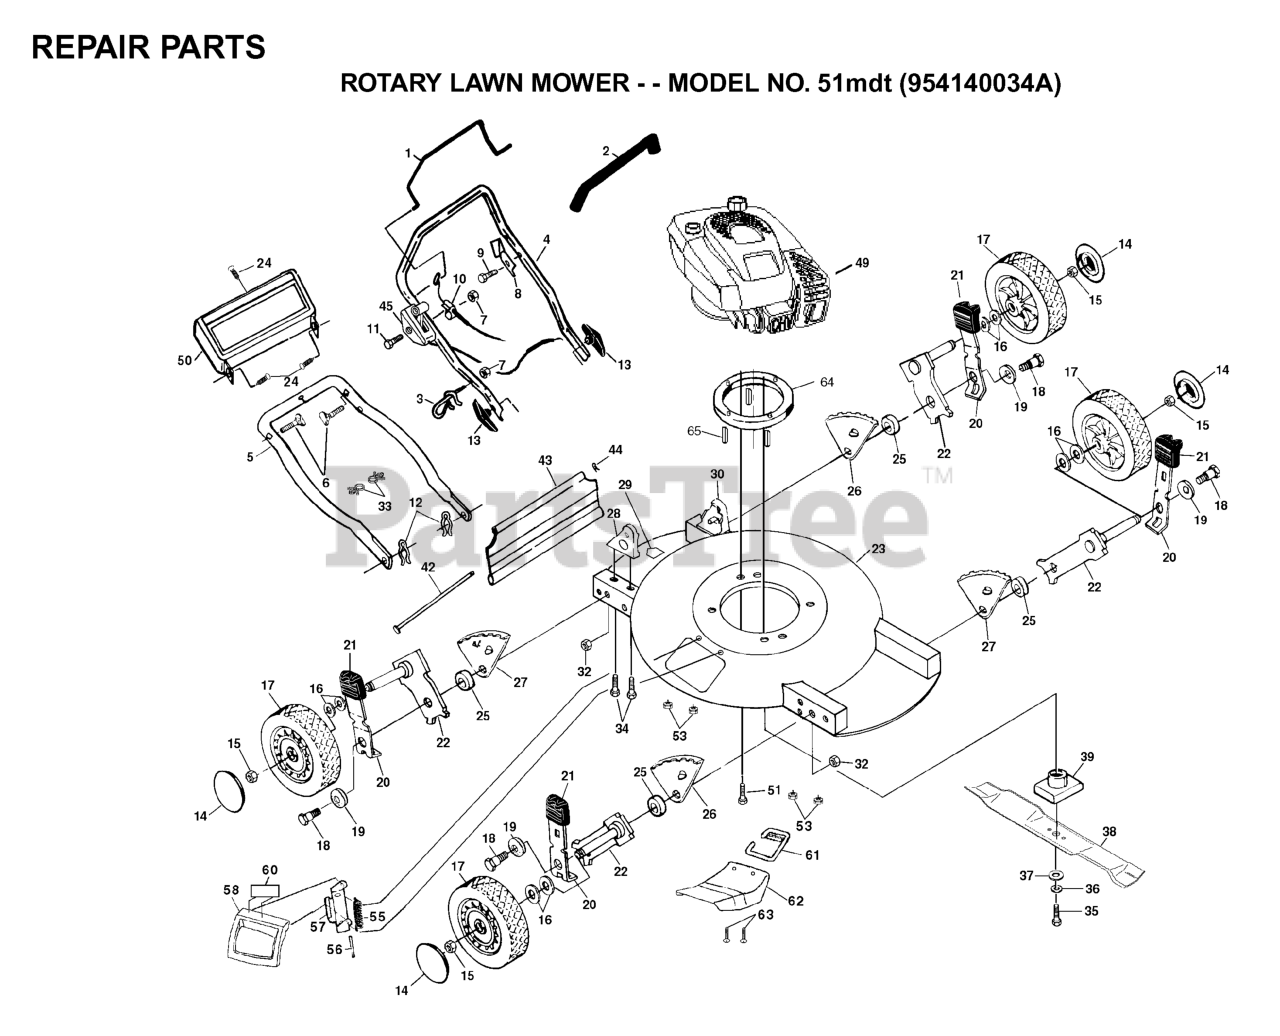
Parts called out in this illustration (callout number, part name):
1	CONTROL BAR/BLACK
2	HANDLE GRIP
3	ROPE GUIDE
4	UPPER HANDLE
5	HANDLE, LOWER
6	HANDLE BOLT
7	NUT
8	BRACKET UPSTOP
9	TAPPING SCREW
10	CABLE.MZR.51.RT.SP./PU.
11	SCREW 1/4-20 X 2.12
12	HAIRPIN COTTER
13	HANDLE KNOB
15	HEX FLANGE LOCKNT
16	WAVE WASHER
18	BOLT
19	WASHER.BELLEVILLE (3 2 LB)
20	SELECTOR SPRING
21	SELECTOR KNOB
22	AXLE ARM
25	RP SPACER HT ADJ
26	WHL ADJ BRKT RF/LR
27	WHL ADJ BRKT LF/RR
28	HDLE BRKT ASSY RH
29	DECAL HYT
30	HDLE BRKT ASSY LH
32	LOCKNUT PM
33	CLIP CABLE SNAP
34	SELF-TAPPING SCREW 5/16-18X3/4
35	SCREW, HEX HD 3/8-24 X 1-3/8
36	LOCKWASHER
37	WASHER,HARDEN
38	BLADE.20.MULCH.(50DK,6020MD)
39	BLADE ADAPTOR
44	RETAINER CLIP
45	THROTTLE CONTROL
50	TRIM PLATE
51	BOLT 3/8-16X1-1/8
53	NUT
55	TORSION SPRING
56	ROD.HINGE.COMBI-C
57	BRACKET PM
58	MULCHER DOOR
61	BRACKET.CHUTE.MTG
62	MULCHER DEFLECTOR
63	Truss Head Screw
